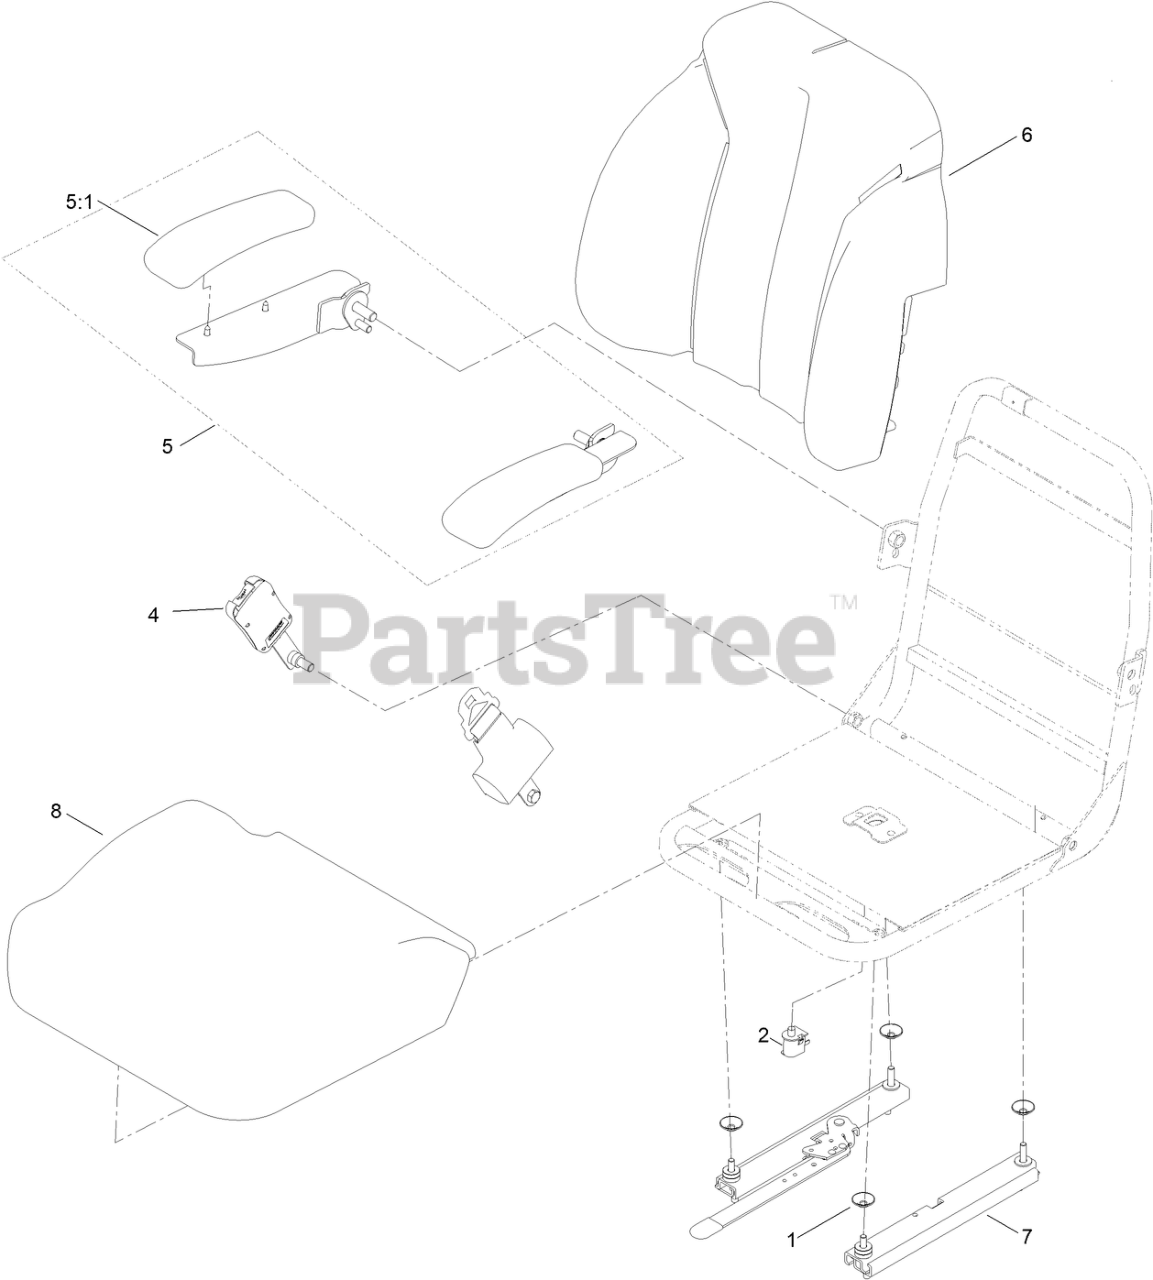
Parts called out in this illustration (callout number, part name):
1	SPACER-MOUNTING
2	SWITCH-BAIL
4	SEAT BELT KIT
5	ARMREST KIT
5:1	CUSHION-REST, ARM
6	COVER-BACK, SEAT
7	TRACK-SEAT
8	COVER-SEAT, BOTTOM
